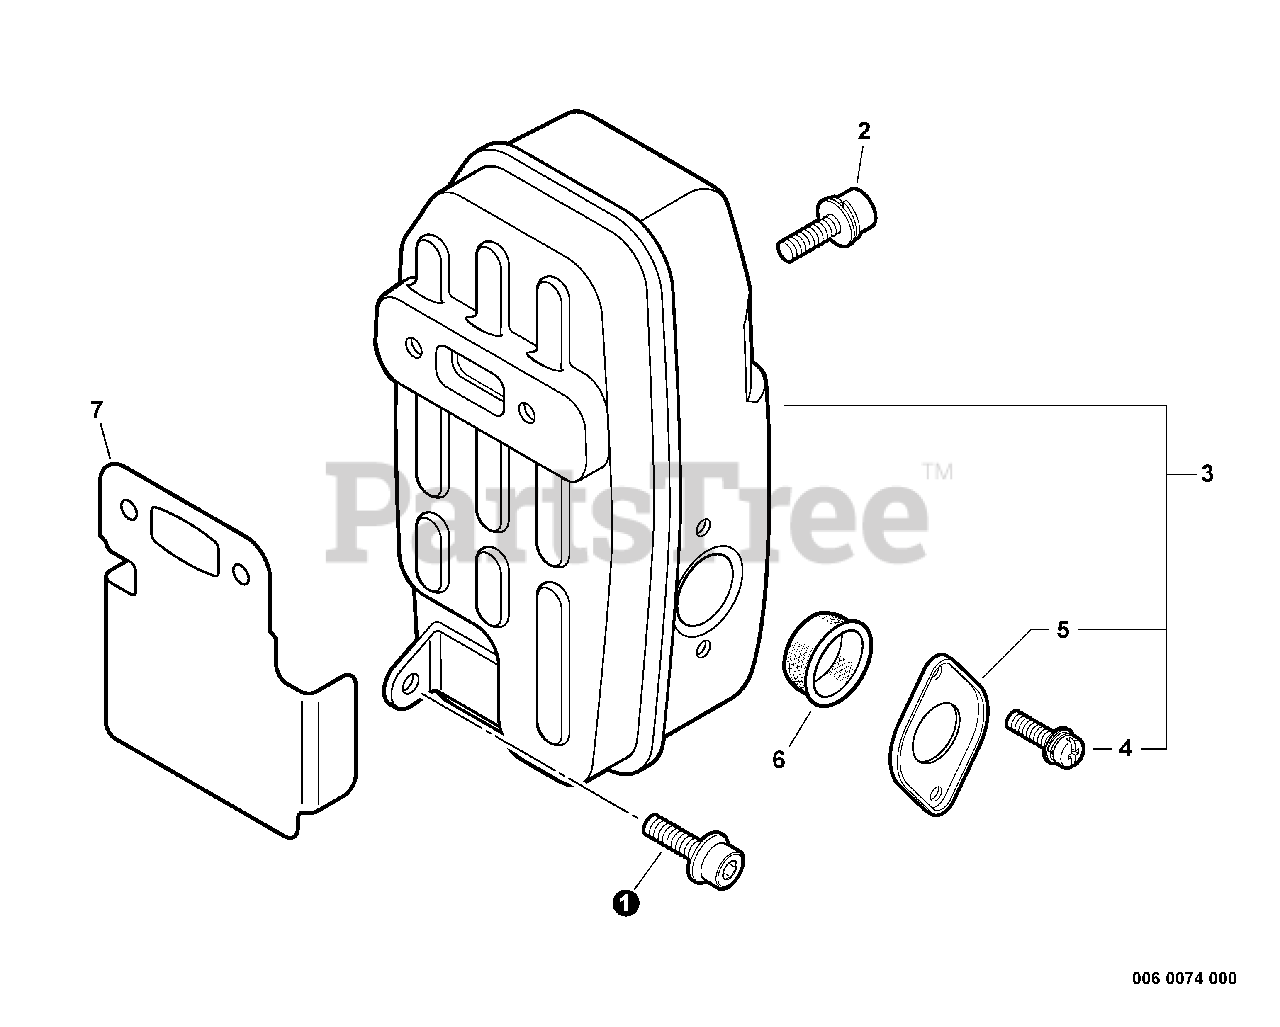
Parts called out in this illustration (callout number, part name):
1	SCREW - 5X14
2	SCREW - 6X20
3	MUFFLER ASSY
4	SCREW - 4X10
5	GUIDE, EXHAUST
6	SCREEN, SPARK ARRESTOR
7	SHIELD, EXHAUST
